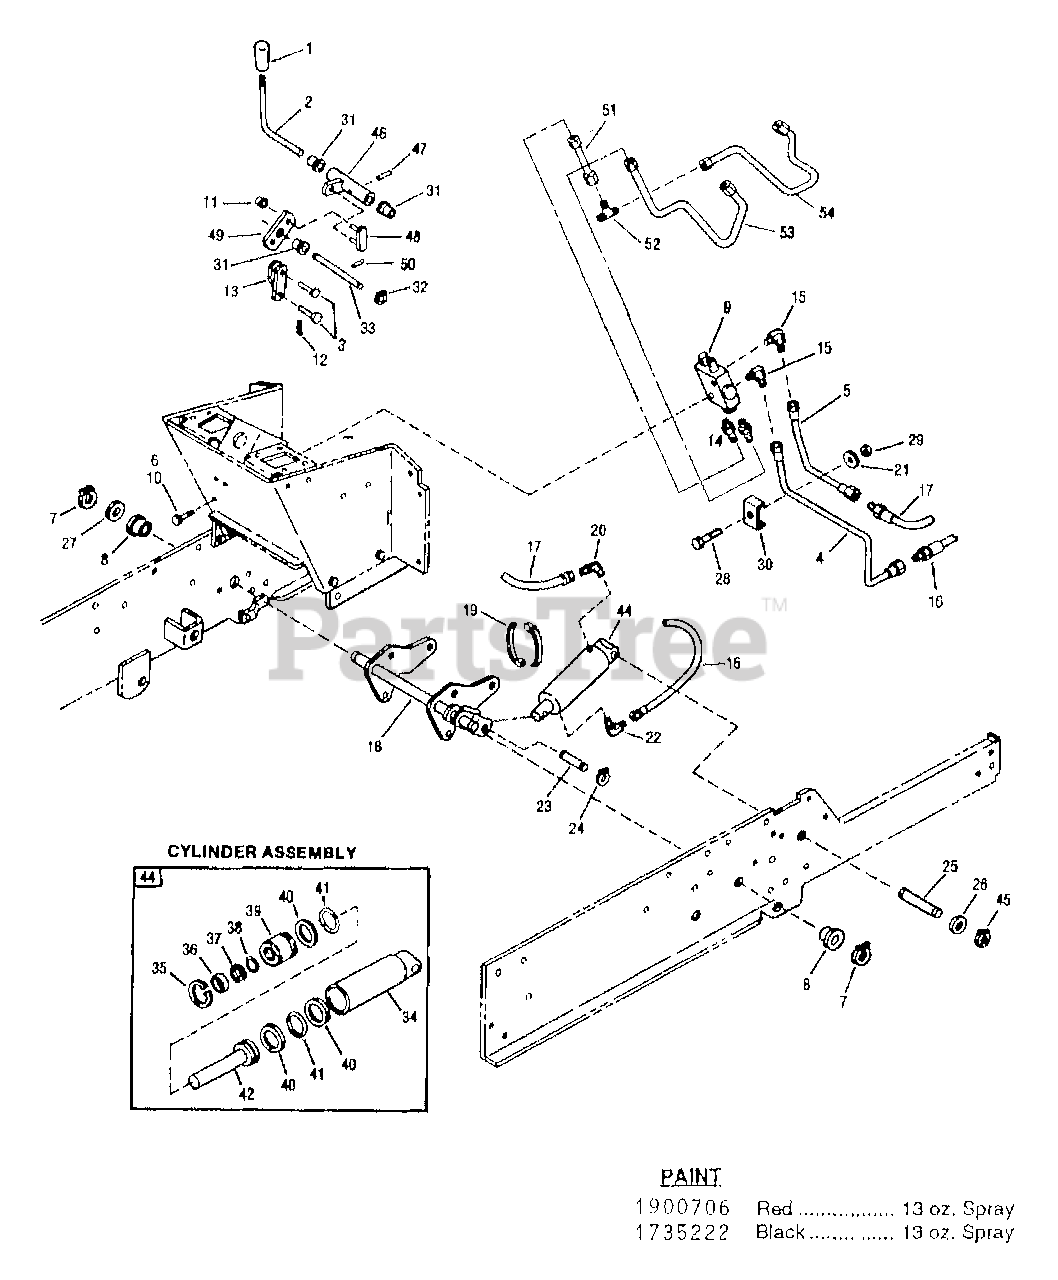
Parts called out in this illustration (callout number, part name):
1	KNOB-SHIFT LEVER
2	LEVER-CONTROL
3	PIN-CLEVIS .25X.81
4	ASSM-TUBE
5	ASSM-TUBE
6	SCR-HFLK 1/4-20X2.00 G5ZP
7	RING-RETAINING
8	BUSHING-FLANGE
9	VALVE-LIFT & AUX.
10	NUT-HF/LK 1/4-20 ZP
11	NUT-PUSH
12	PIN-COTTER
13	ASSM-VALVE LINK
14	CONNECTOR
15	ELBOW
16	ASSM-HOSE
17	ASSM-HOSE
18	SHAFT-LIFT
19	TIE-CABLE NYLON BLACK
20	ELBOW
21	WASHER-FLAT 1.25X.406X.179
22	ELBOW
24	RING-RETAIN .625 ID
26	WASHER-1.5X.755X.062
27	WASHER-SPEC
28	SCR-HH 5/16-18X1.0 G5 ZP
29	NUT-TOP/LK 5/16-18 ZP
30	CLAMP
31	BRG-FLANGE
32	RING-RETAINING
33	PIN-PIVOT
34	ASSM-CYL HYDRAULIC
35	RING-RETAIN INT 2.210 DIA
36	SEAL-OIL
37	RING-BACK/UP
38	RING-O .984 ID
39	HEAD-CYLINDER
40	RING-BACK/UP
41	RING-O 1.6 ID
42	ASSM-ROD HYDR CYLINDER
44	ASSM-CYL HYDRAULIC
45	RING-RETAIN EXT .707 ID
46	ASSM-CONTROL ARM
47	PIN-DRIVE
48	ASSM-CONTROL LINK
49	ARM-ROCKER
50	PIN-ROLL .125 X .62
51	ASSM-TUBE
53	ASSM-TUBE
54	ASSM-TUBE
